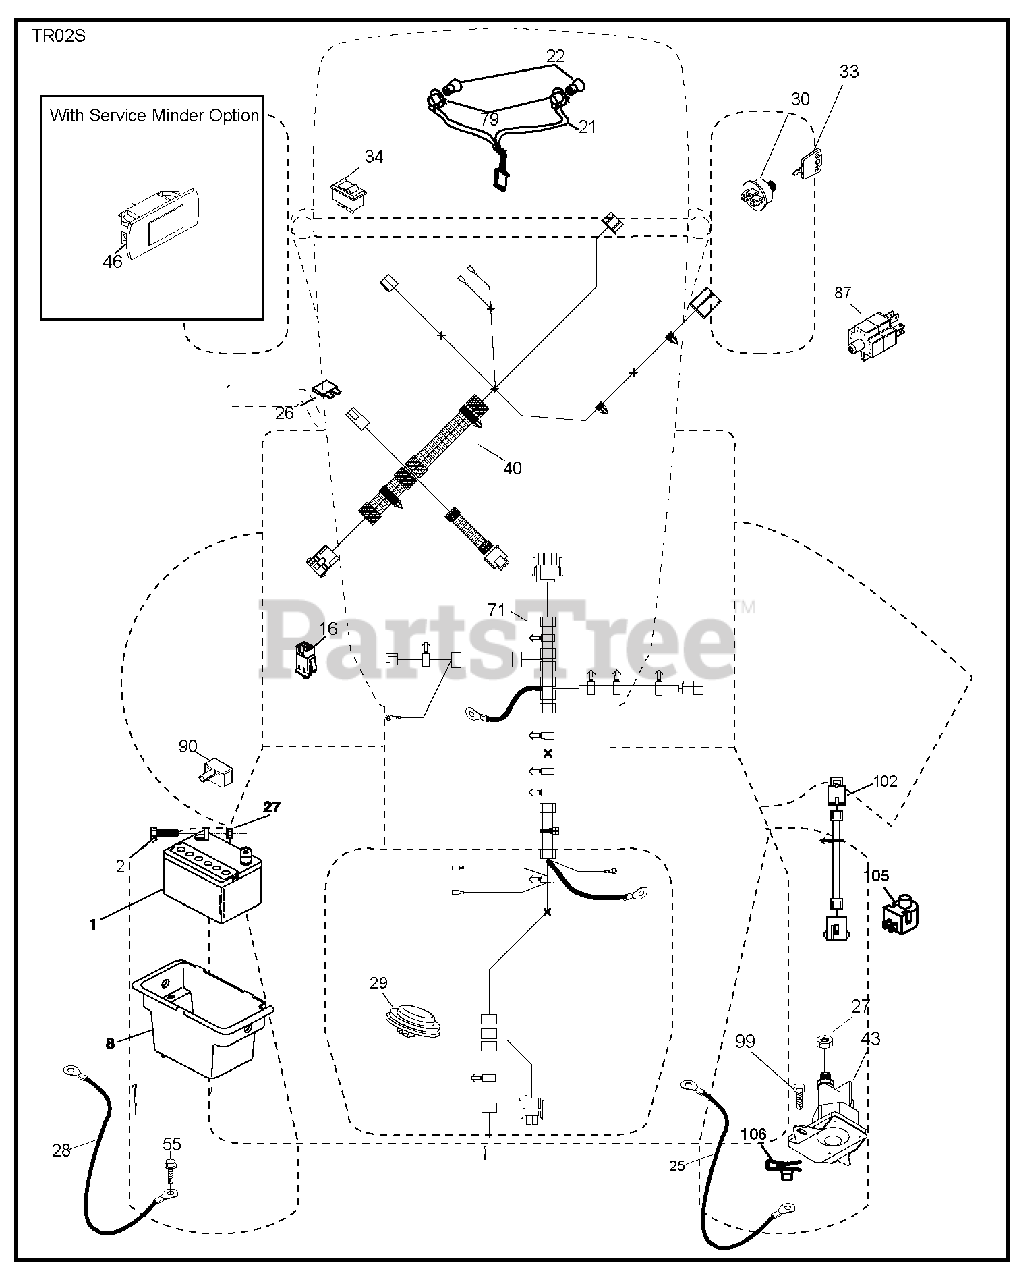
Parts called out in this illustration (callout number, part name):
1	REPL BY 532 12 38-99
8	BOX.BATTERY.MNT.REAR.L
16	SWITCH INTERLOOK PUSH-IN
21	HARNESS.LIGHT W/4152J BULBS
22	LIGHTBULB
25	Positive Battery Cable, Red 8 Ga 17
26	FUSE 20AMP
27	NUT
29	SWITCH.SEAT.DELTA.OPC.
30	SWITCH.IGN.DELTA.W.LGH.ROS
33	KEY.CHAIN.BLISTER.PACK.GEN.USA
34	SWITCH LT
40	Dash Harness, Tex Rear Batt
43	SOLENOID.W/BRASS.PLUNG
46	Hour Meter Gauge
55	SCREW 5/16"
71	Harness, Tex Chssis.Rear.Batt
79	BULB HOLDER ASM.
87	SWITCH.INTRLCK.CLUTCH.
90	COVER.TERMINAL.BATTERY
99	SCREW HEXWSHR 1/4-20X3/4
102	HARNESS PIGTAIL PCH TEX ROS
105	REVERSE SWITCH
106	1/4-20 U NUT
